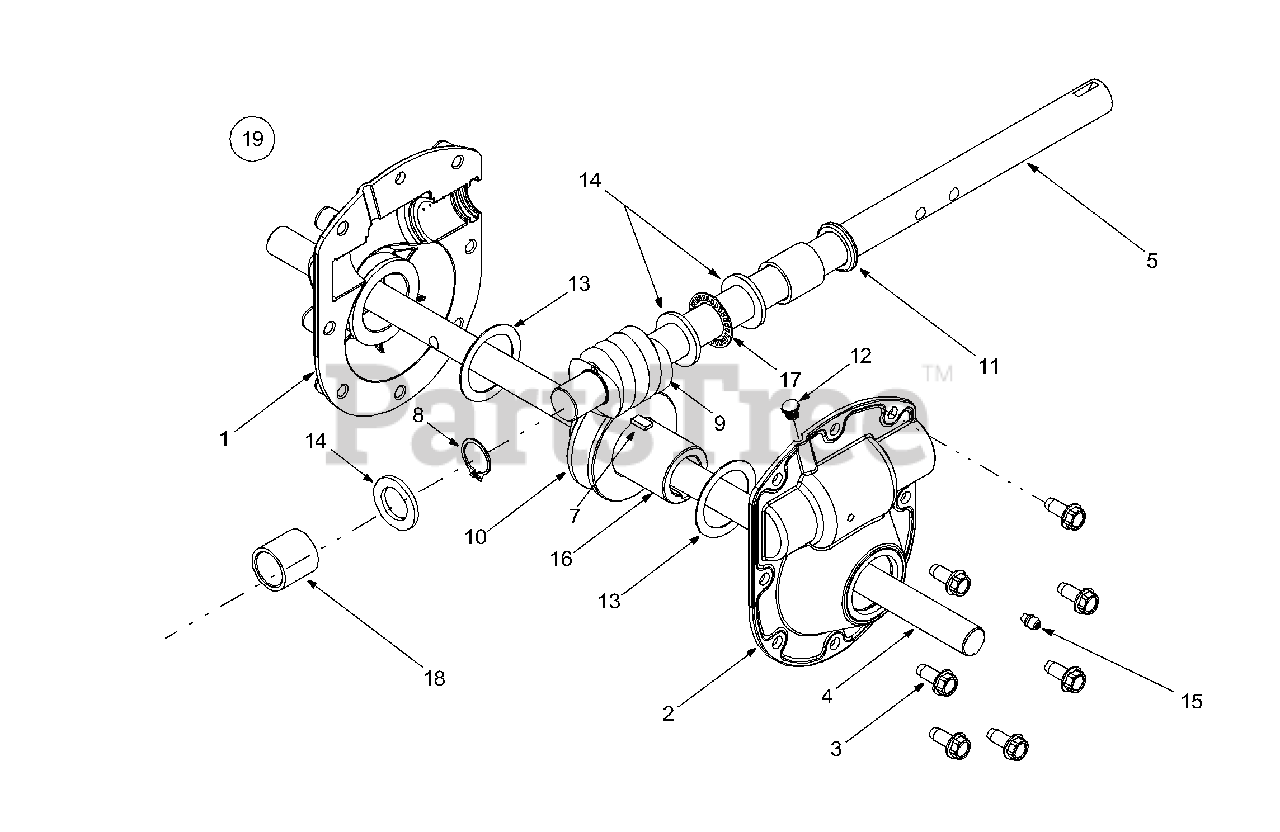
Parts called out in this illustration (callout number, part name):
1	Housing Assembly, RH
2	Housing Assembly, LH
3	Screw, 5/16-18 x 0.75
4	Axle, Auger
5	Shaft, Auger Drive
6	Key, Hi Pro, 3/16 x 3/4
7	#91 Woodruff Key 1/4 x 3/4
8	Snap Ring .875 Dia.
9	Gear, Worm, Double Thread LH
10	Gear, Worm, LH
11	Seal, Oil .875 ID
12	Plug, 1/4 x .437
13	Washer, Flat, 1.52 x 2.0
14	Washer, Flat, .88 x 1.38
15	Lube Fitting, 3/16 Drive
16	Shaft, Worm Gear
17	Bearing, Thrust .877
18	Sleeve Bearing, .877 x .125 x 1.11
19	Auger Gearbox Assembly Complete
